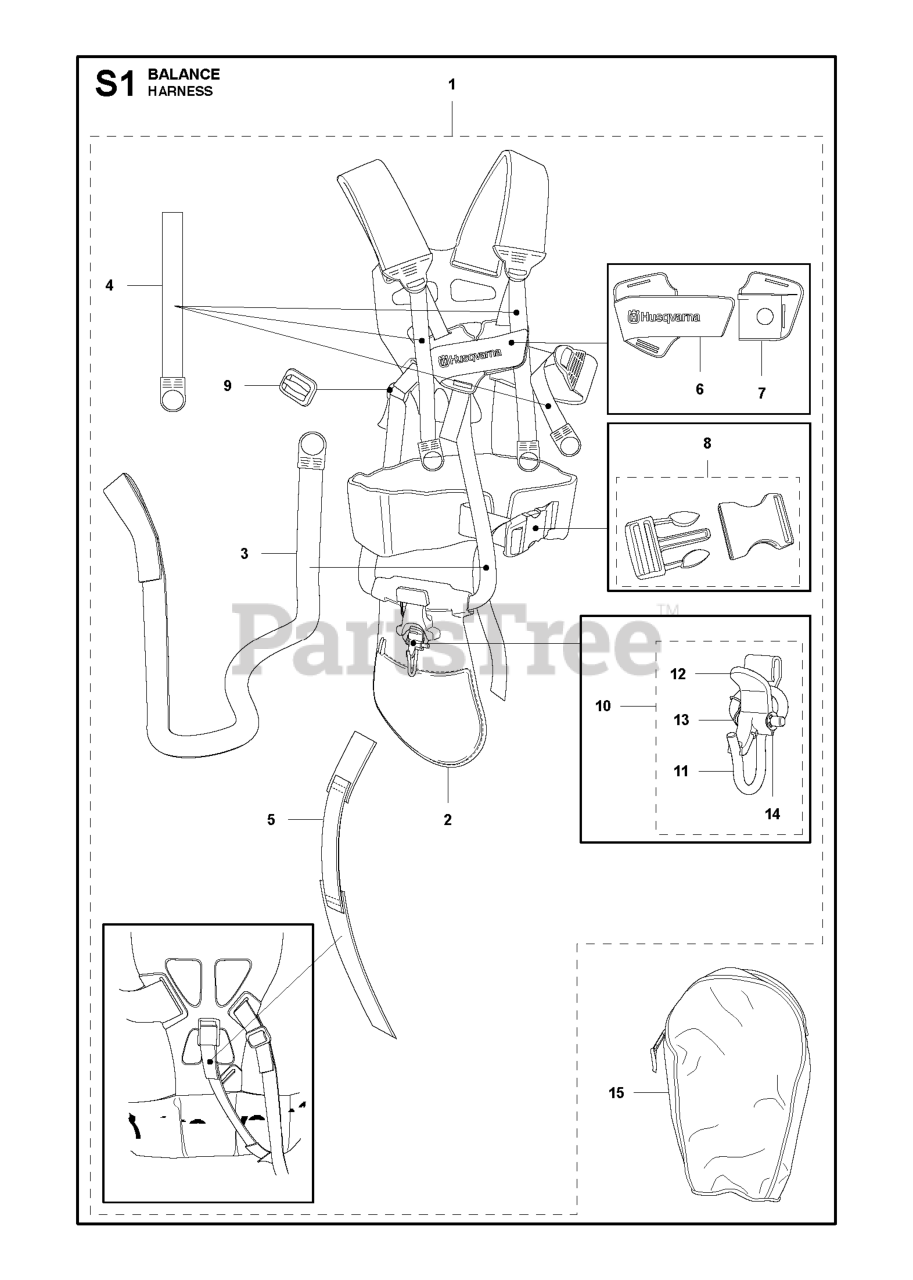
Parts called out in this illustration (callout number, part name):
1	RP HARNESS TRIO BALANCE
1	HUS BALANCE X TRIO HARNESS
6	FRONT PIECE
7	FRONT PIECE
9	RP CLIP
11	HOOK
12	CATCH *
13	SPRING LOCKING
15	TOOL BAG
